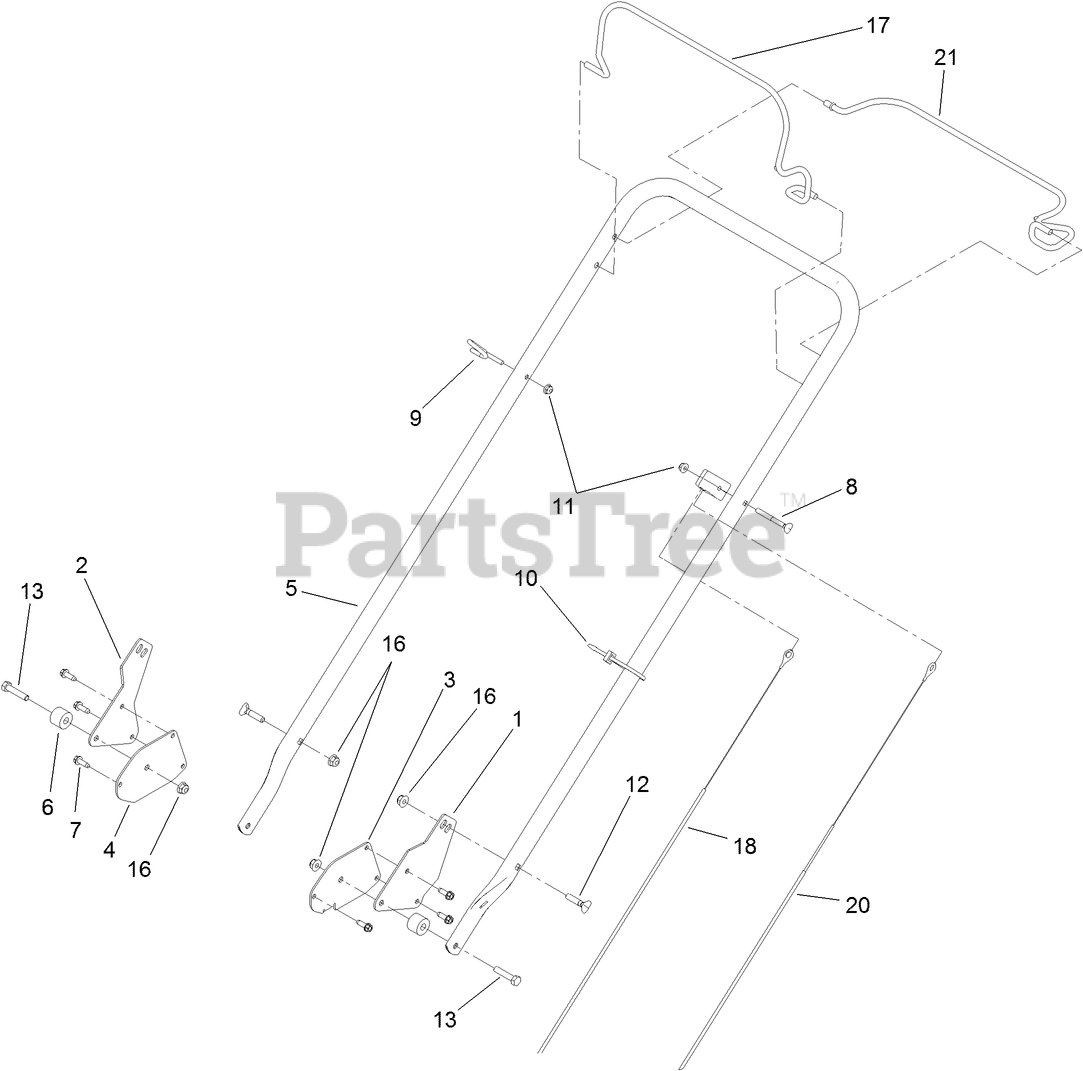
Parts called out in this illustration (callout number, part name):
1	SUPPORT-STRUT, LH
2	SUPPORT-STRUT, RH
3	PLATE-HANDLE, TRACTION
4	PLATE-HANDLE
7	SCREW-HWHTF
8	SCREW-HANDLE
9	GUIDE-ROPE
10	TIE-CABLE
11	NUT-HF
12	SCREW-HANDLE
13	SCREW-HH
16	NUT-HF, NI
17	BAIL-BRAKE
18	CABLE-BRAKE
20	CABLE-TRACTION
21	BAIL-TRACTION
